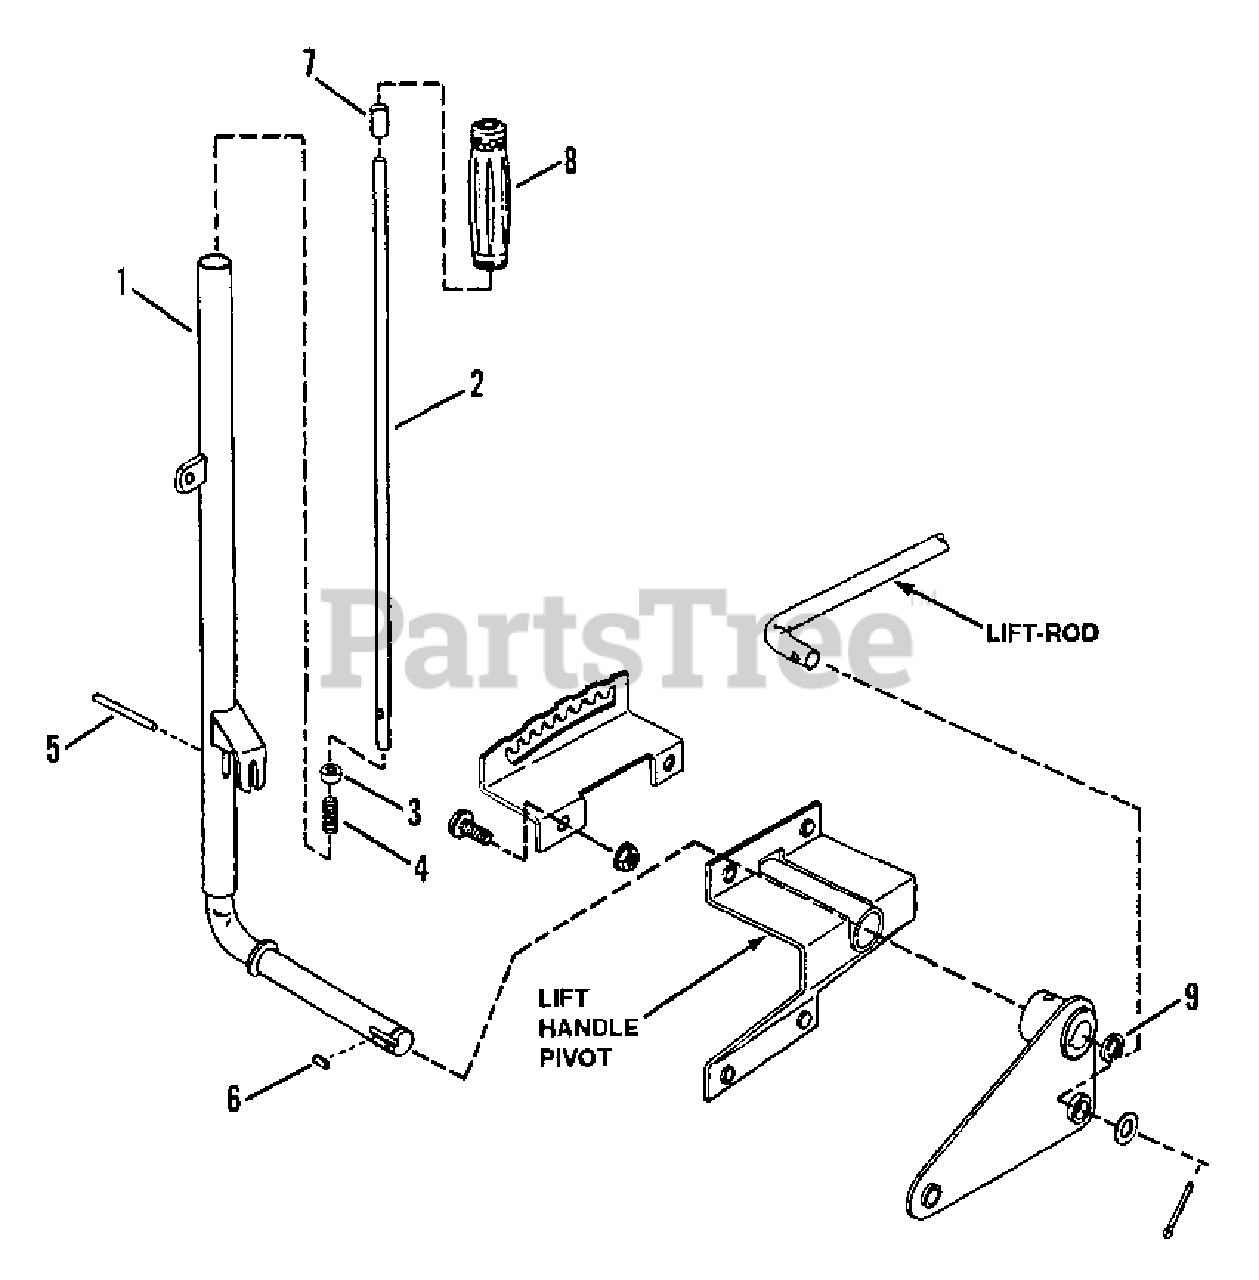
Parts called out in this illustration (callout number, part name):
1	WELDMENT, Lift Handle
2	PLUNGER
3	PLUG, Nylon
4	SPRING
5	PIN, 3/16 x 2" Groove
6	KEY, 1/4 x 1" Square
7	CAP, Lift Release
8	GRIP, Handle
9	RING, 7/8" External Retaining
